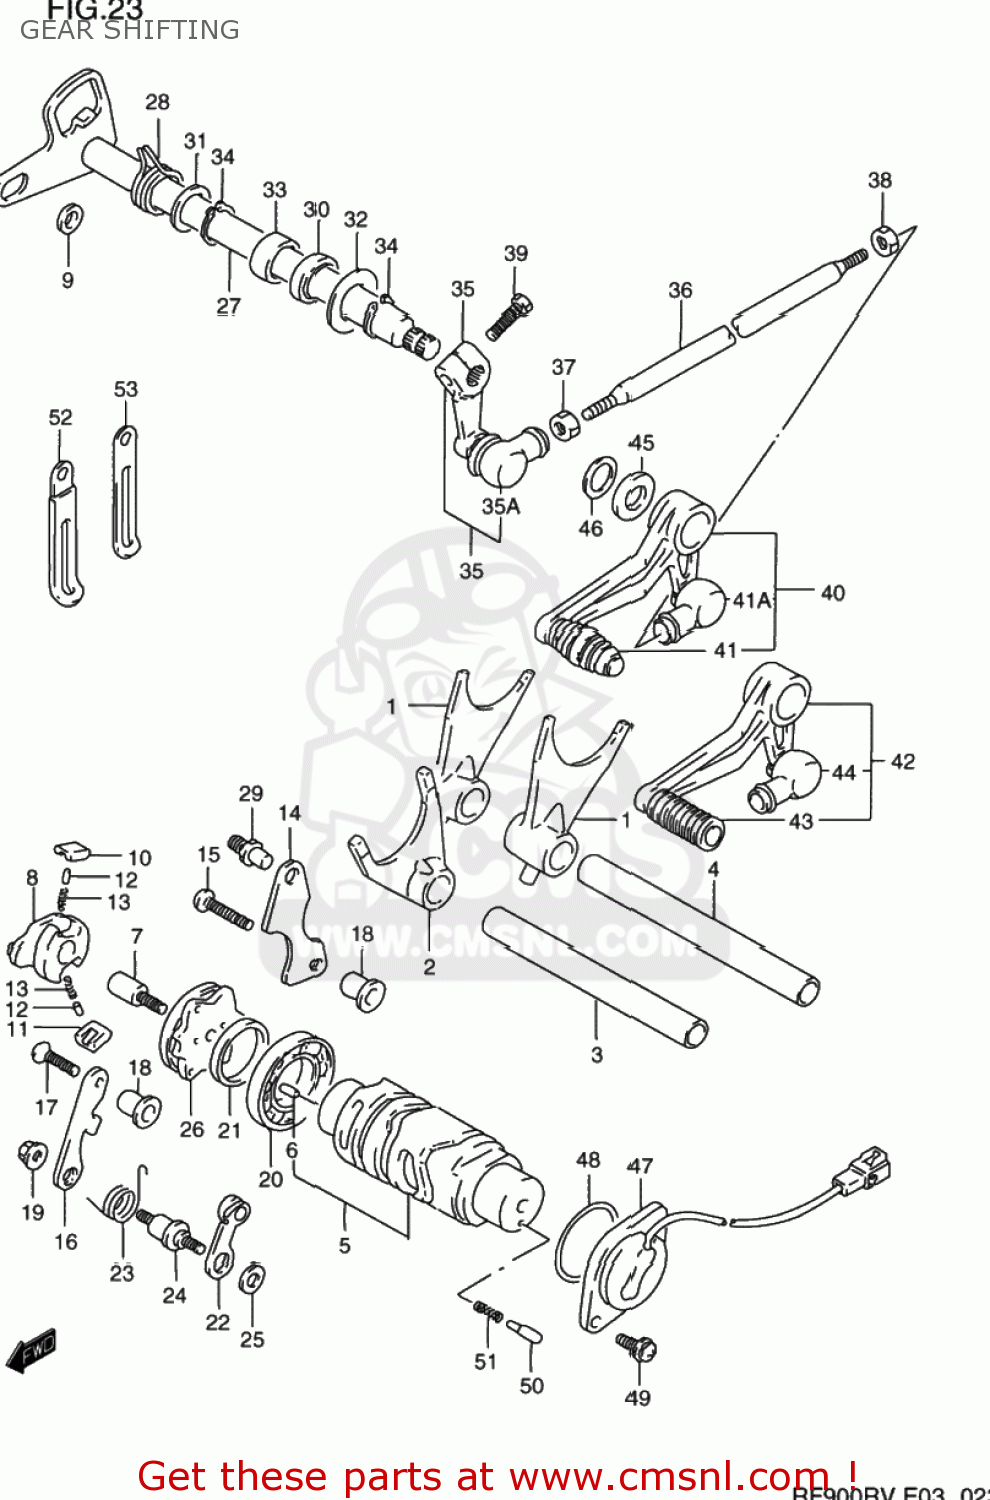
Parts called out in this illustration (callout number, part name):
1	FORK,GEAR SHIFT NO.1
2	FORK,GEAR SHIFT NO.3
3	SHAFT,GEAR SHIFT FORK
4	SHAFT,GEAR SHIFT FORK(L:128)
5	CAM,GEAR SHIFT
6	PIN
7	PIN,SHIFT CAM DRIVEN GEAR
8	SHIFTER,GEAR SHIFT CAM
9	SPACER(7X10X5)
10	PAWL,GEAR SHIFT NO.1
11	PAWL,GEAR SHIFT NO.2
12	PIN(5X8)
13	SPRING
14	LIFTER,GEAR SHIFT PAWL
15	SCREW 6X30
16	GUIDE,GEAR SHIFT CAM
17	SCREW
18	SPACER(6.1X10X16)
19	NUT
20	BEARING(25X47X8)
21	WASHER(25X32X3)
22	STOPPER,GEAR SHIFT CAM
23	SPRING,STOPPER ARM
24	SUPPORT,CAM STOPPER ARM
25	WASHER
26	PLATE,GEAR SHIFT CAM
27	SHAFT,GEAR SHIFT
28	SPRING
29	STOPPER,GEAR SHIFT CAM
30	SEAL,OIL(14X22X6)
31	WASHER,THRUST
32	WASHER(14X29X0.8)
33	BEARING(14X20X12)
34	CIRCLIP
35	ARM,GEAR SHIFT LINK
35A	COVER,DUST
36	ROD,GEAR SHIFT LINK
37	NUT
38	NUT
39	BOLT
40	LEVER ASSEMBLY,GEAR SHIFTING
41	RUBBER,GEAR SHIFT PEDAL
41A	COVER,DUST
42	LEVER ASSY,GEAR SHIFT
43	RUBBER,GEAR SHIFT PEDAL
44	COVER,DUST
45	WASHER(14X27X4)
46	WASHER(18X24X1)
47	TERMINAL BASE ASSY,NEUTRAL
48	O RING(D:2.4,ID:35.5)
49	SCREW
50	PIN(5X15.5)
51	SPRING
52	CLAMP L:35
53	CLAMP
